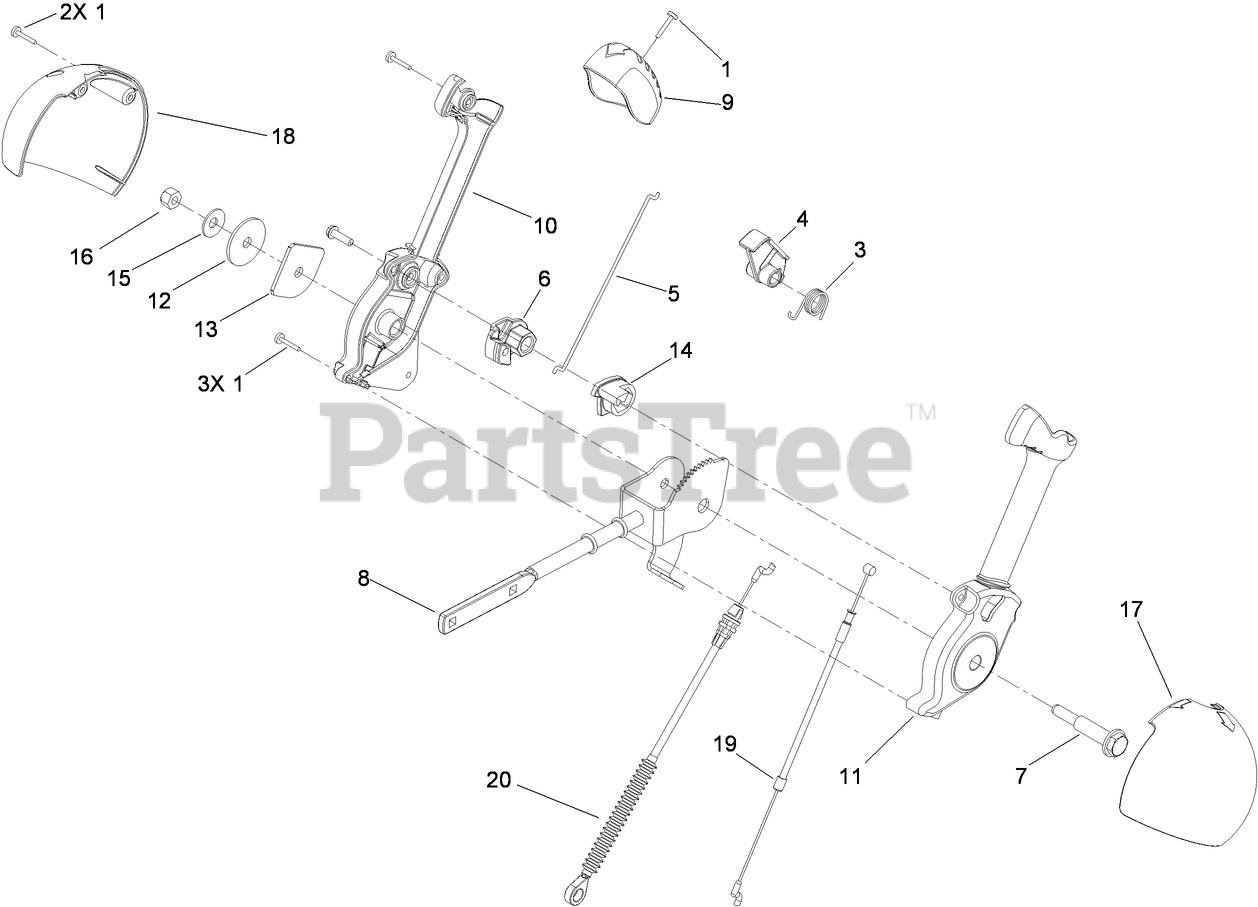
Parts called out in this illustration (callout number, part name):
1	SCREW-PPH
3	SPRING-TORSION
4	TRIGGER-LATCH
5	LINK-LATCH
6	LEVER-CABLE, DEFLECTOR
7	SCREW-SHOULDER
9	CAP-LEVER
10	LEVER-CONTROL, CHUTE (RH)
11	LEVER-CONTROL, CHUTE (LH)
12	WASHER-NYLON
14	PAWL-LATCH
15	WASHER-BELLEVILLE
16	NUT-LOCK, NI
17	COVER-LEVER, CHUTE (LH)
18	COVER-LEVER, CHUTE (RH)
19	CABLE-RELEASE, CHUTE
20	CABLE-CONTROL, DEFLECTOR
